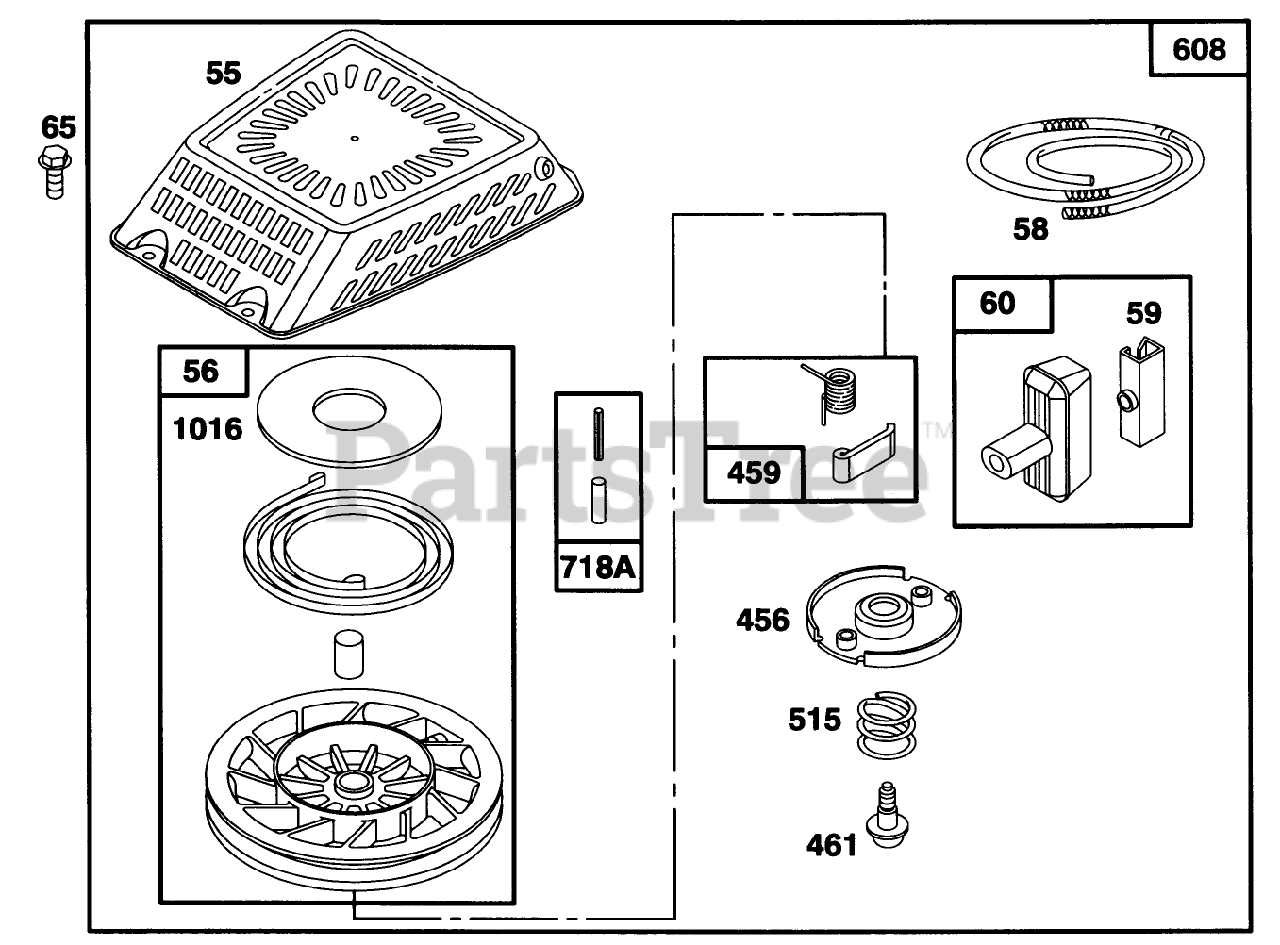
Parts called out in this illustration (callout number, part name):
59	INSERT-HANDLE, REWIND
456	Retainer-Rewind Starter
459	Pawl-Starter
515	SPRING - RETAINER
1016	Cover-Spring
